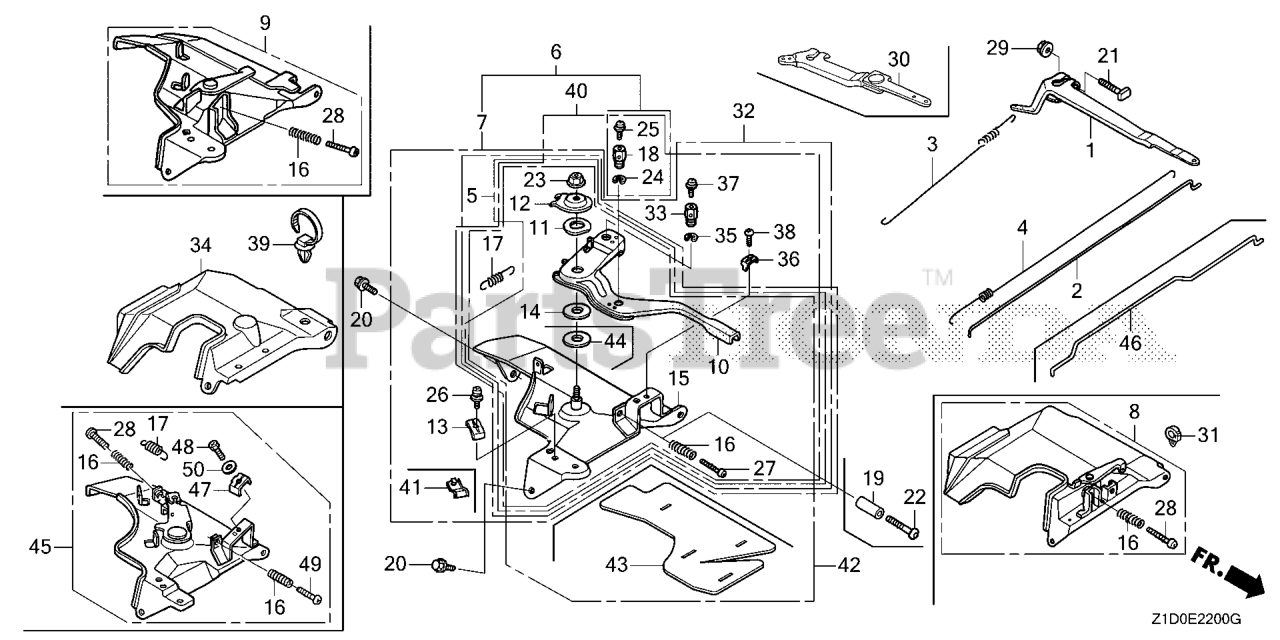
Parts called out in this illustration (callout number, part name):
1	ARM, GOVERNOR
2	ROD, GOVERNOR
3	SPRING, GOVERNOR (L=145.0MM) (WIRE DIAMETER 1.0MM)
4	SPRING, THROTTLE RETURN
9	CONTROL ASSY. (COO)(FOR U.S.A.)
9	CONTROL ASSY.
16	SPRING, CONTROL ADJUSTING Use from Engine SN 2327377.
20	BOLT, FLANGE (6X12) (CT200)
21	BOLT, GOVERNOR ARM
28	SCREW, PAN (5X35)
29	NUT, FLANGE (6MM)
